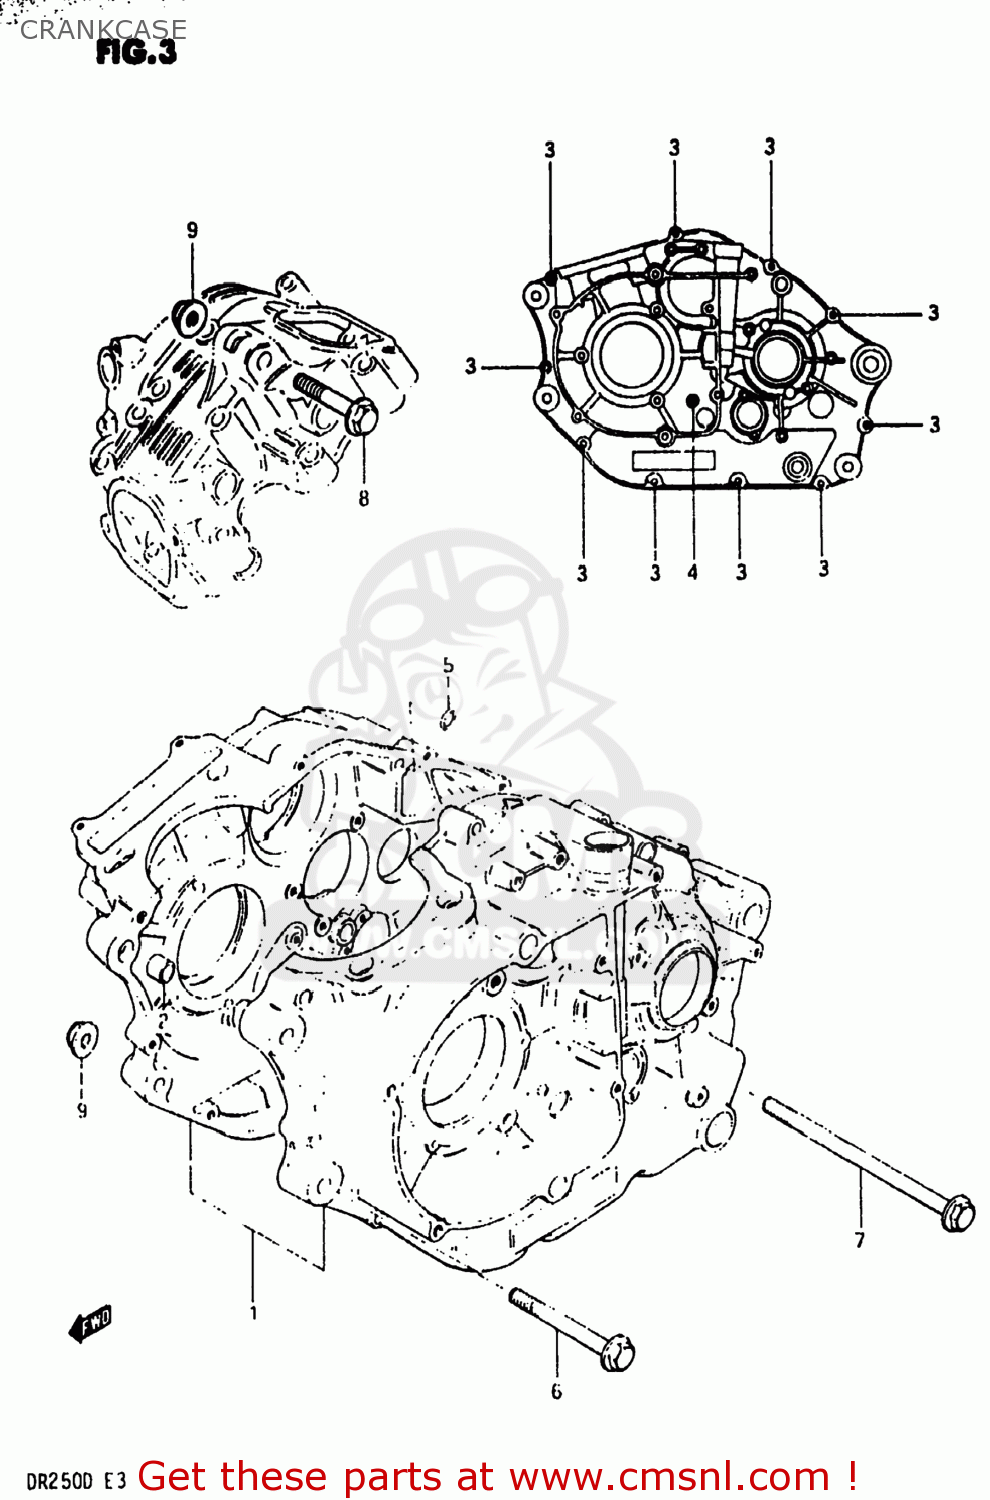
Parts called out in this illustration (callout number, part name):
1	CRANKCASE ASSEMBLY
2	PIN
3	BOLT (6X35)
4	BOLT (6X55)
5	O-RING
6	BOLT 8X67
7	BOLT
8	BOLT 8X50
9	NUT
